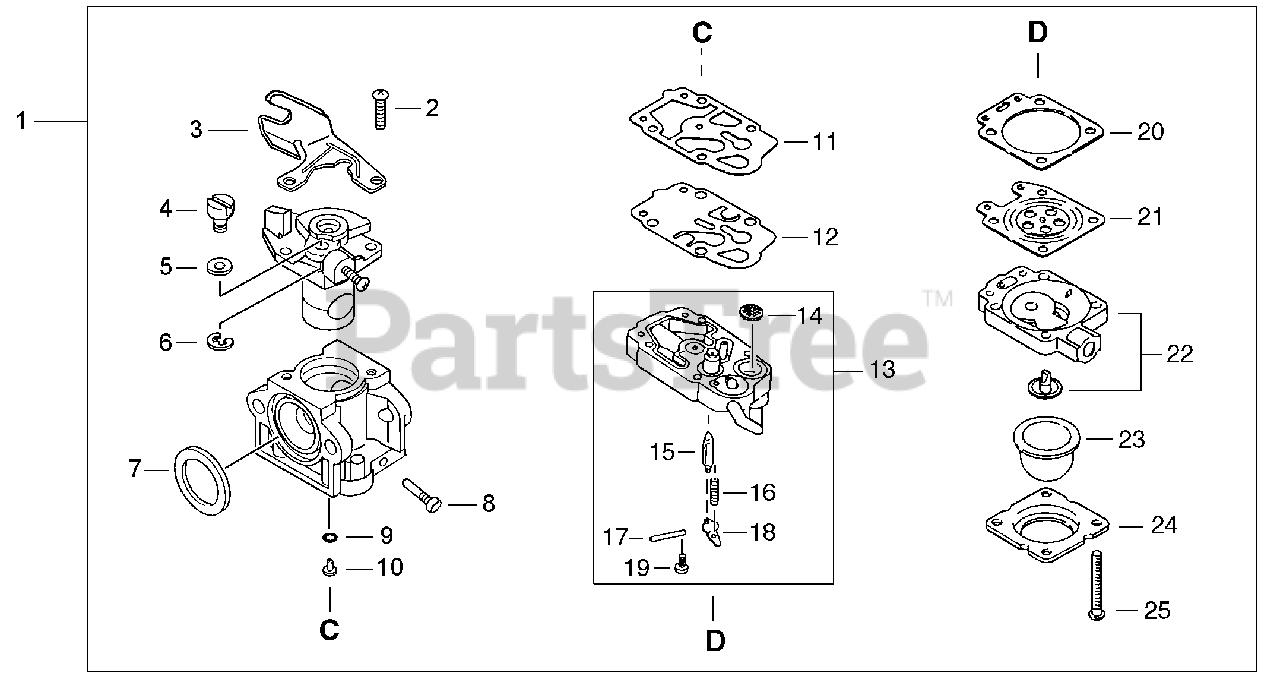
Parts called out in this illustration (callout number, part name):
1	CARBURETOR - WYK-201
3	BRACKET, THROTTLE CABLE
7	RING, PACKING
8	NEEDLE, HIGH SPEED
9	O-RING
10	JET, MAIN
11	GASKET, PUMP
12	DIAPHRAGM, FUEL PUMP
13	BODY ASSY, PUMP
14	SCREEN, FUEL INLET
15	VALVE, INLET NEEDLE
16	SPRING, METERING LEVER
17	PIN, METERING LEVER
18	LEVER, METERING
20	GASKET, METERING DIAPHRAGM
21	DIAPHRAGM, METERING
22	BODY ASSY, PURGE
23	BULB, PURGE
24	RETAINER, PURGE BULB
